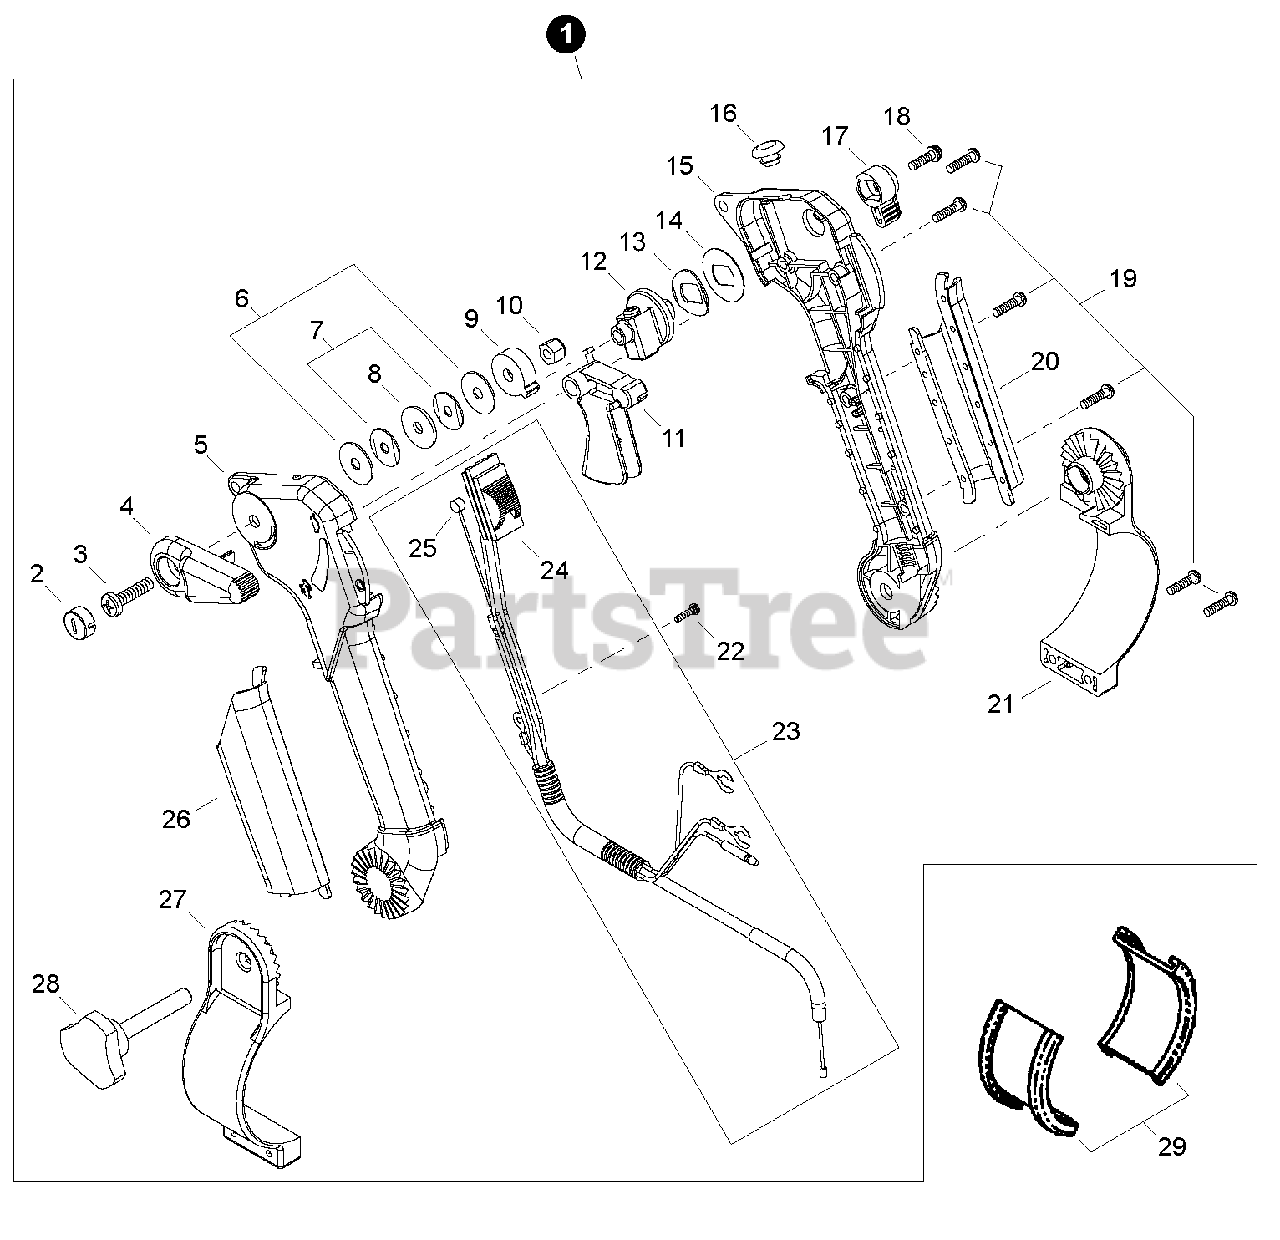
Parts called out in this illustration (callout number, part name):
1	CONTROL HANDLE ASSY
2	CAP, BOLT
3	SCREW - 6
4	LEVER, THROTTLE CONTROL
5	HANDLE, CONTROL - LEFT
6	WASHER - 6
7	WASHER - SPRING
8	WASHER - 6
9	LEVER, THROTTLE
10	NUT - 6 -- NYLON
11	TRIGGER, THROTTLE
12	THROTTLE LIMITER ASSY
13	WASHER - WAVE
14	WASHER
15	HANDLE, CONTROL - RIGHT
16	PLUG, THROTTLE LIMITER
17	LEVER, THROTTLE LIMITER
18	SCREW - 4
19	SCREW - 4
20	GRIP, HANDLE - RIGHT
21	BRACKET - RIGHT
22	SCREW - 3
23	CONTROL CABLE ASSY
24	SWITCH, IGNITION
25	CABLE, THROTTLE
26	GRIP, HANDLE - LEFT
27	BRACKET, HANDLE - LEFT
28	THUMBSCREW
29	SPACER
